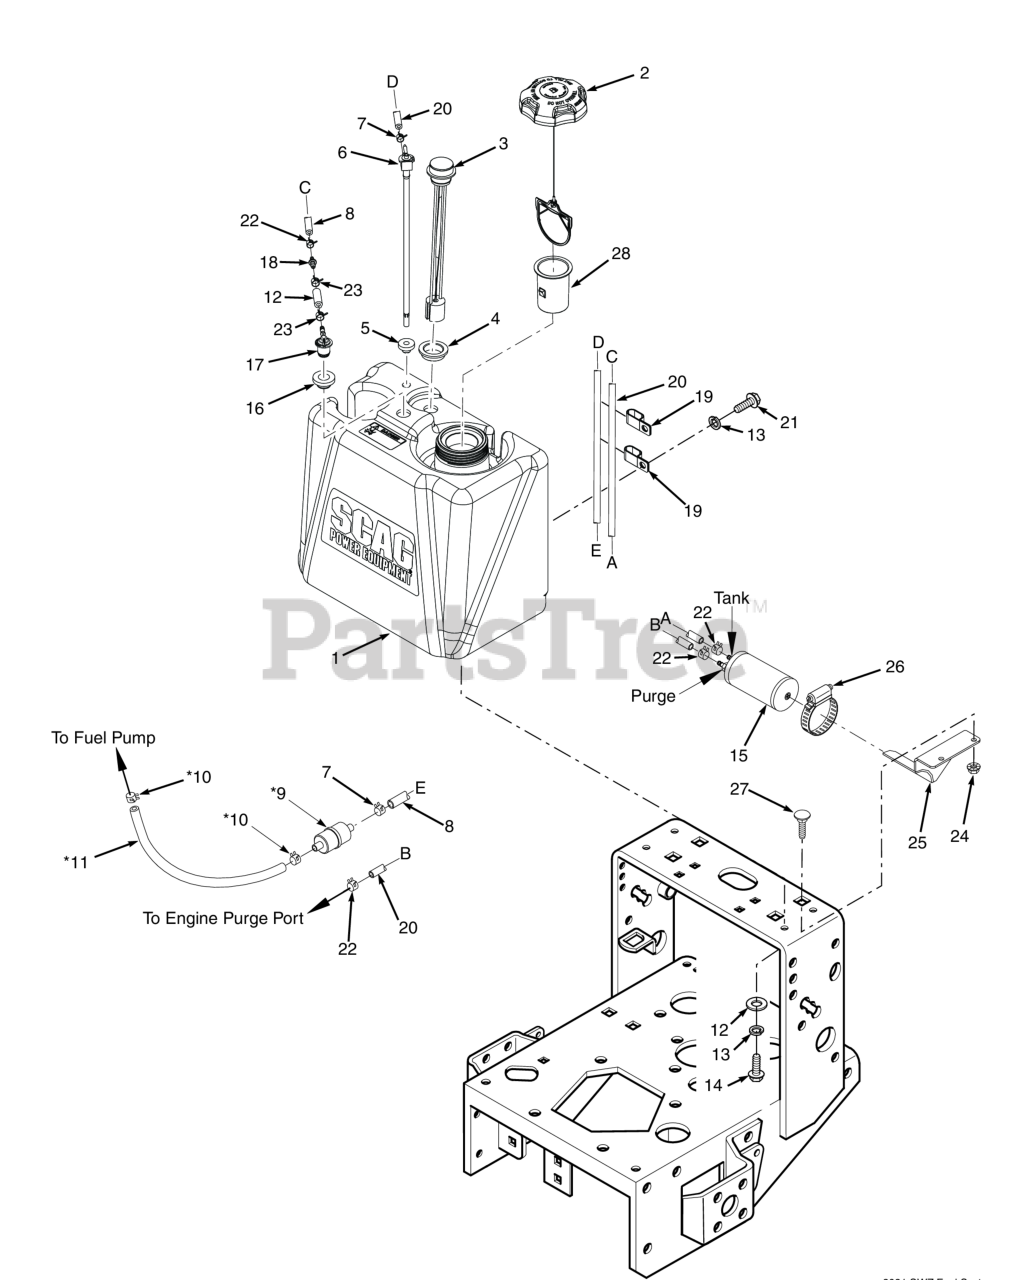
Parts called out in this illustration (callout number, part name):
1	Fuel Tank Assembly (incl. #2, 3, 5, 6, 17, 18)
2	Fuel Cap w/ Tether (E.P.A.)
3	Fuel Gauge Assembly
4	Grommet, Fuel Gauge
5	Bushing, 0.56" Dia. Viton
6	Valve, Fuel Shutoff w/Screen
7	Clamp, Fuel Hose 1/4" Hose I.D.
8	Fuel Hose, 1/4" I.D. Non-Perm (791DFI Fuel Return) - Order by Inch
9	Fuel Filter
10	Clamp, Fuel Hose
11	Fuel Hose
12	Hose, 1/4" Vapor Recovery (order by inch)
13	Lockwasher, 5/16 (.317 x .586 x .078) Helical Spring
14	Bolt, Heax Head 5/16-18 x 1" (48V / 52V)
15	Carbon Canister - SVR-36A / SVR-48V
16	Grommet, Viton,
17	Remote Vent, No Valve
18	Mender, 1/4 x 3/16 w/0.02 Hole
19	Clamp, Double Cable 5/8" ID.
20	Hose, Vapor Recovery 3/16" (order by inch)
21	BOLT, SERRATED FLANGE HEX HEAD 5/16-18 X 3/4"
22	Clamp, Vapor Recovery Hose 3/16"
23	CLAMP, FUEL HOSE(KAWASAKI ONLY)
24	Nut, Serrated Flange 5/16-18 (Right Front Engine Mounting, Briggs and Kohler Only)
25	Bracket, Canister Mounting
26	Clamp, 3-1/2" Max. Dia.
27	Bolt, Carriage 5/16-18x1" (large frame units only)
28	Tube, Fuel Tank Insert - 4"
